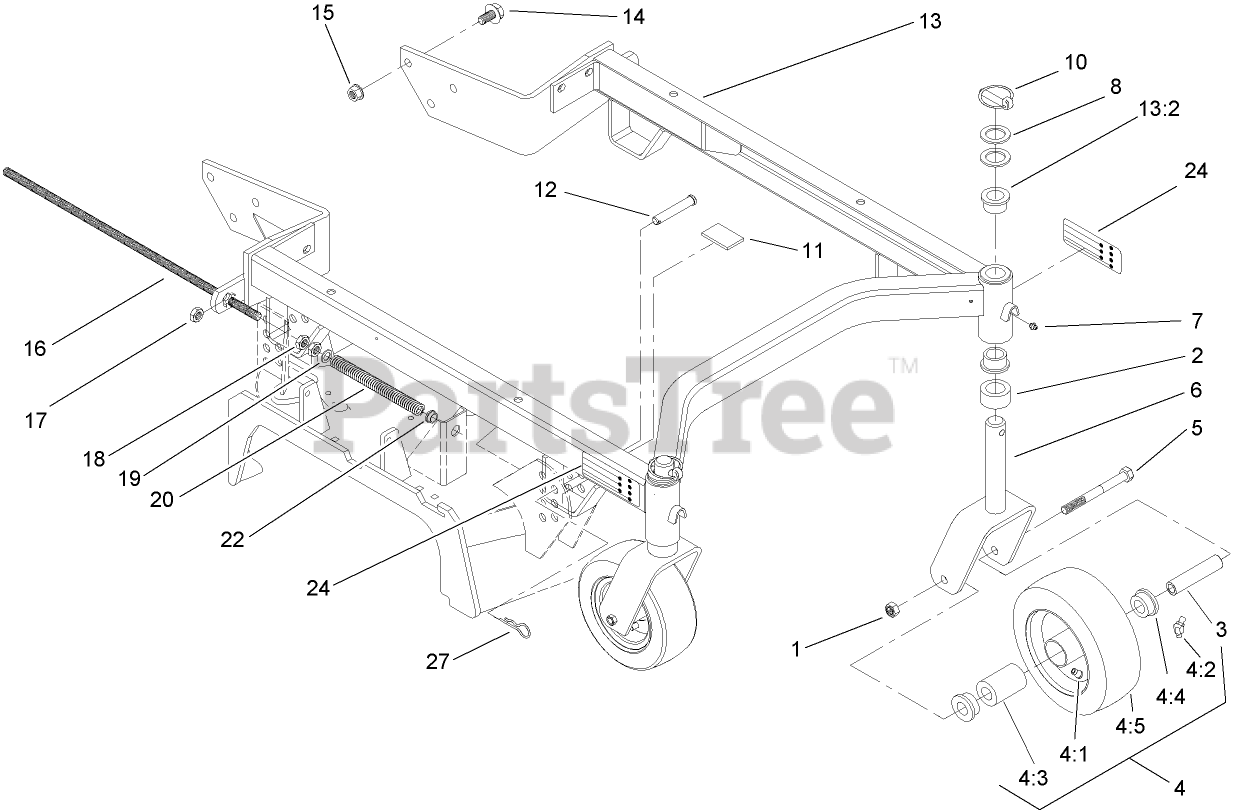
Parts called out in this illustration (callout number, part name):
1	NUT-HEX
2	SPACER-CASTOR
3	BUSHING-SPANNER
4	CASTER WHEEL ASM
4:1	STEM-VALVE
4:2	FITTING-LUBE, 45 DEG
4:3	BEARING
4:4	BEARING-OUTSIDE
4:5	TIRE-TUBELESS
5	SCREW-HH
6	CASTOR FORK ASM
7	FITTING-GREASE
8	WASHER-THRUST
10	PIN-LYNCH
11	CUSHION-RUBBER
12	PIN-CLEVIS
13	FRAME ASM
13:2	BUSHING
14	SCREW-HHF
15	NUT-HF
16	SHAFT-ADJUSTING
17	NUT-LOCK, NI
18	NUT-JAM
19	WASHER
20	SPRING
22	BUSHING-FLANGE
24	DECAL-HOC
27	PIN-HAIR
